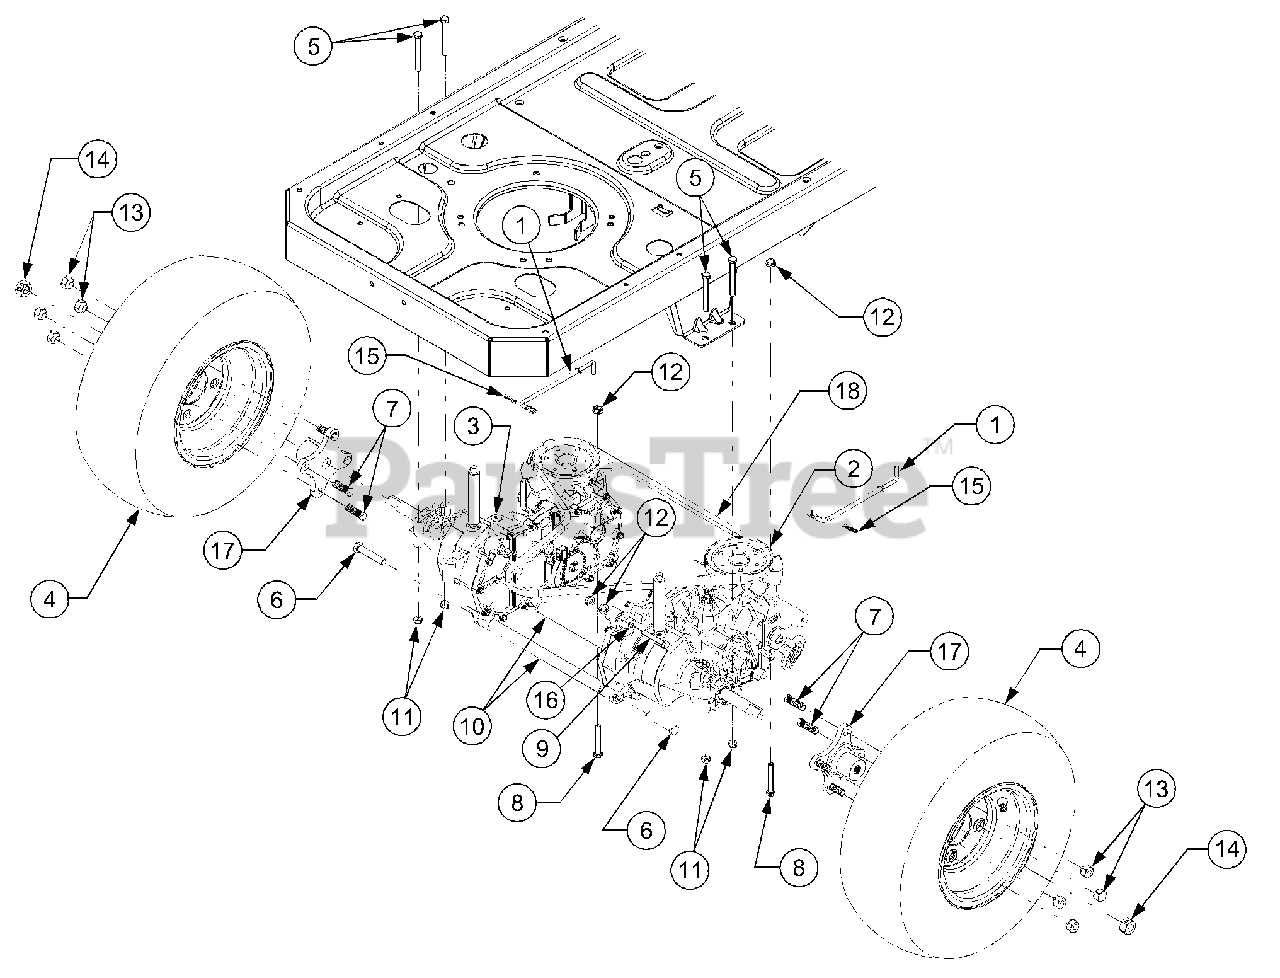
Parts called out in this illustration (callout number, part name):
1	Rod, Bypass
2	Transmission Assembly, RH, Service Kit
3	Transmission Assembly, LH, Service Kit
4	Wheel Assembly, 18 x 6.5 x 8
5	Screw, Hex Cap, 5/16-18 x 2.75 GR5
6	Screw, Hex Lock, 7/16-14 x 2.25 GR5
7	Stud, Rib Neck, 7/16-14 x 1.6
8	Screw, Hex Cap, 5/16-18 x 2.25 GR5
9	Screw, Hex Cap, 5/16-18 x 2.0 GR5
10	Brace, Transmission
11	Nut, Hex Insert Lock, 5/16-18 GR5
12	Nut, Hex Flange Lock, 5/16-18 GR5
13	Nut, Lug, 7/16-14
14	Nut, Hex Lock, 9/16-18 GR "C"
15	Pin, Internal Cotter
16	Washer, Flat, .344 x .688 x .065
18	V-Belt, Type A Sec x 57.7
